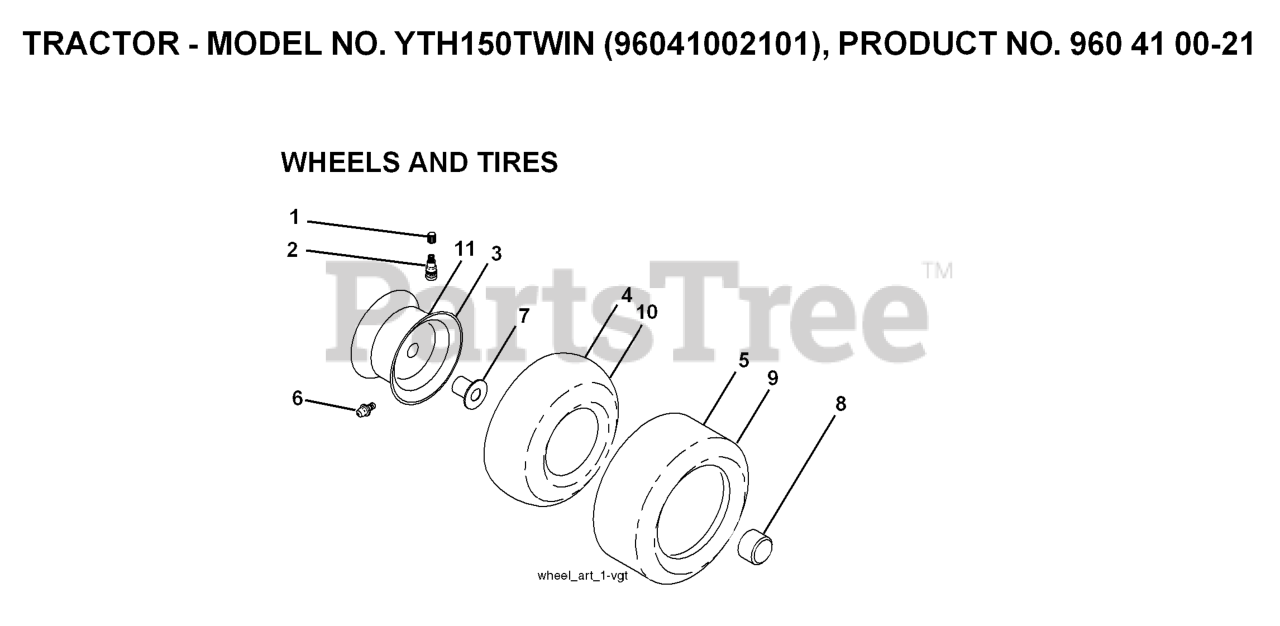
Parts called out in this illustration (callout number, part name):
2	VALVE STEM LT
3	RIM ASM 6" FRONT SILVER
4	TUBE.5.3/4.5/6
5	TIRE HEAVY DUTY
6	FITTING LT
7	BEARING T
8	CAP, AXLE BLK
9	TIRE.TS.20X10-8
10	TUBE
11	RIM ASM 8" REAR SILVER
